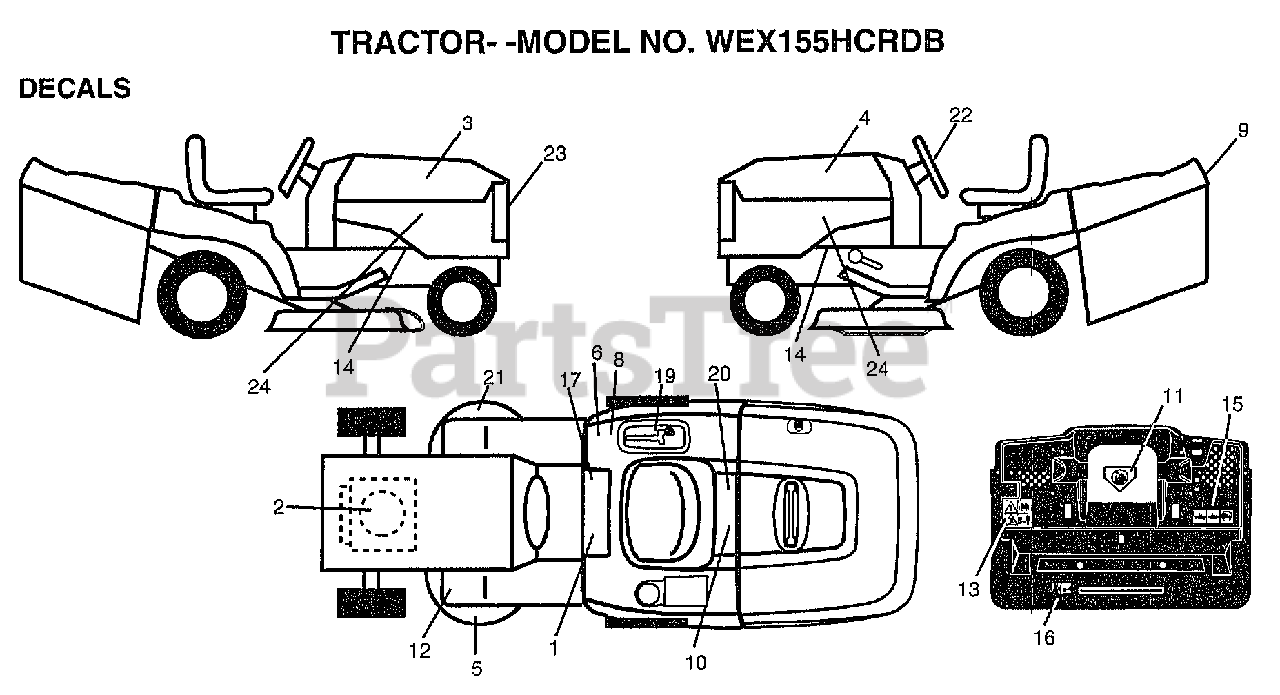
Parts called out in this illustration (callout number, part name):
1	DECAL.READ.O.MANU
3	DECAL.HOOD.RH.
4	DECAL.HOOD.LH
5	DECAL, DECK GRASSEATER
8	DECAL.EURO.ST.CE.
9	DECAL.FENDER.LOGO
10	DECAL.BATRY.3-3908
11	DECAL.DANGER.CUTF
12	DECAL-BRAKE/CLUTC
13	DECAL.WARNING.BACKPLATE.CRD
14	"DECAL CHASSIS,HOT"
15	DECAL, OPER BAG
16	DECAL.DRAWBAR.LDL
17	DECAL BRAK PARK
19	DECAL.BYPASS.FENDER.CRD.
20	DECAL.BYPASS.FENDER.CRD.LT.YT
21	DECAL.DECK.HEX.BELT
22	DECAL, INS STRG WH
23	DECAL, GRILLE LENS
24	DECAL.PANEL.SD
